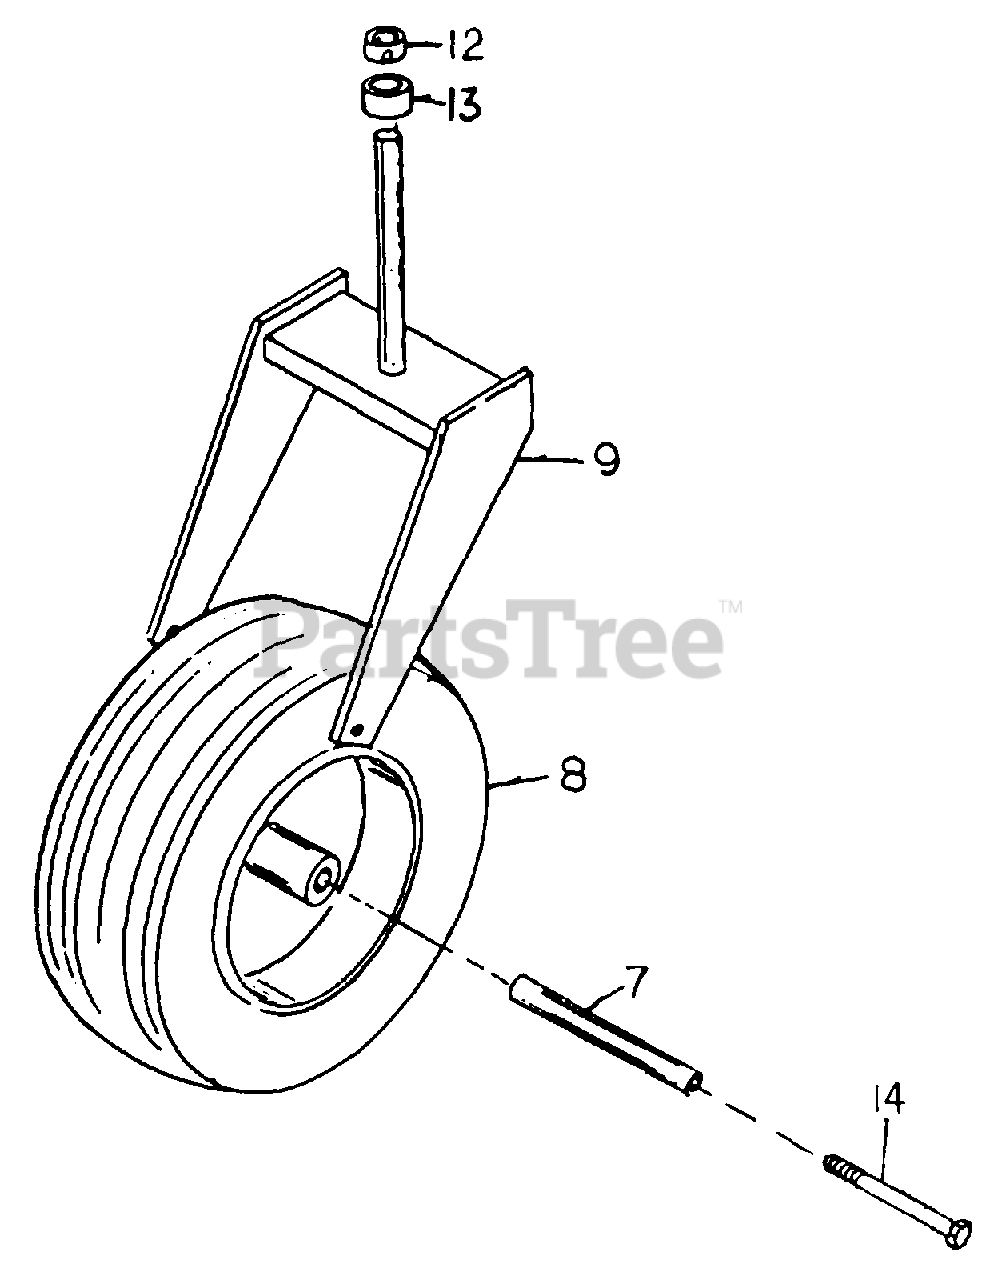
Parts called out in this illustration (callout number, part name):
7	Axle
8	Tail Wheel Assembly
9	Tail Wheel Fork
12	Set Collar, 1"
13	Spacer, Tail Wheel Fork
14	Hex Capscrew, 1/2-13 x 8 1/2"
